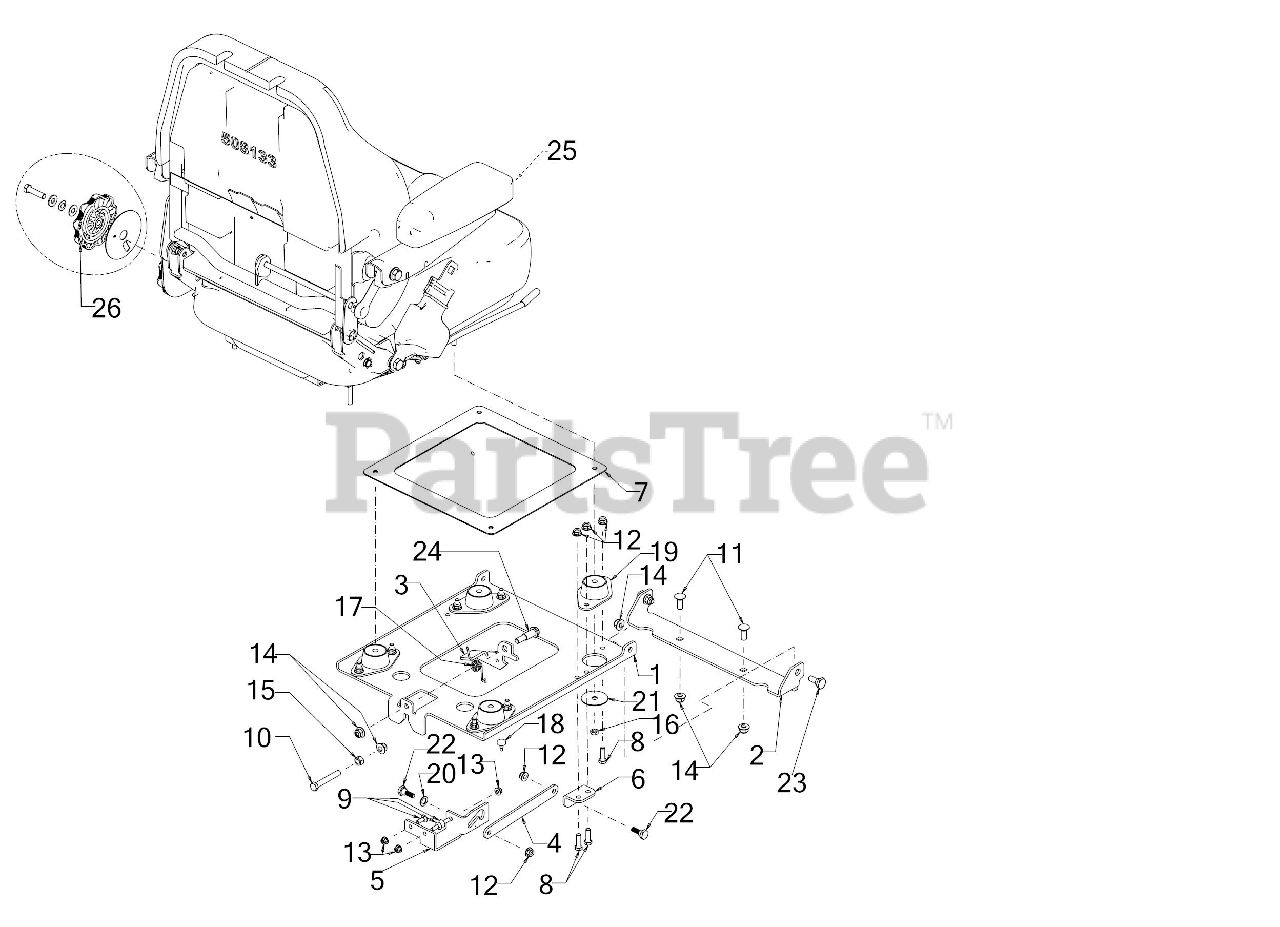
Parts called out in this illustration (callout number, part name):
4	SEAT LOCKOUT BRACKET
5	SEAT LOCKOUT MOUNT
8	SCREW 5/16-18 x 1.0 GR5
9	SCREW 1/4-20 x .75 GR5
10	HEX SCREW-3/8-16X2.5 GR5
11	CARRIAGE BOLT 3/8-16 x 1.00 GR5
12	FLANGE LOCK NUT 5/16-18
13	FLANGE LOCK NUT
15	HEX NUT
16	HEX NUT TOP LOCK 5/16-18 GR 8
17	TORSION SPRING
18	RUBBER BUMPER
19	SEAT MOUNT
20	FLAT WASHER .469X.750X.054
21	HUB CAP WASHER .406 x 1.92 x .060
22	SHOULDER SCREW .437 DIA x .265
23	SHOULDER SCREW
24	SHOULDER SCREW .50X.925
25	SEAT W/SUSPENSION & LUMBAR ADJUST
26	SEAT KNOB KIT
